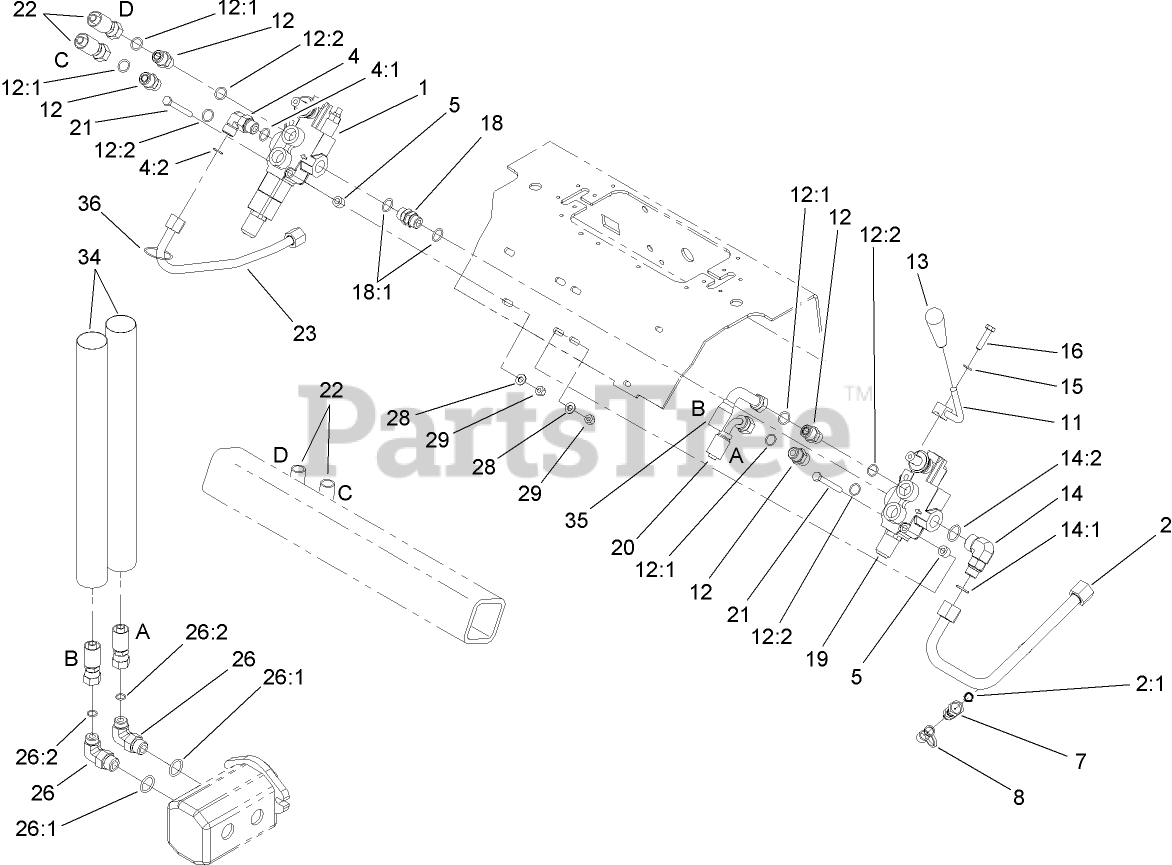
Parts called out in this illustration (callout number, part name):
1	VALVE-HYD, AUXILIARY
2	HYD TUBE ASM
2:1	O-RING
4	FITTING-ELBOW-90 DEG
4:1	O-RING
4:2	O-RING
5	SPACER
7	NIPPLE-TEST
8	CAP-DUST
11	LEVER-CONTROL
12	FITTING-STRAIGHT
12:1	O-RING
12:2	O-RING
13	KNOB-TAPERED
14	Fitting-Elbow, 90 DEG
14:1	O-RING
14:2	O-RING
15	WASHER-LOCK
16	SCREW-HH
18	FITTING-THREAD, STRAIGHT
18:1	O-RING
19	VALVE-SELECTOR, HYD
20	HOSE-HYD
21	SCREW-HH
22	HOSE-HYD
23	TUBE-HYD
26	FITTING-ELBOW 90
26:1	O-RING
26:2	O-RING
28	WASHER-PLAIN
29	NUT-LOCK, NI
34	SLEEVE-GUARD, HOSE
35	HOSE-HYD
36	TIE-CABLE
